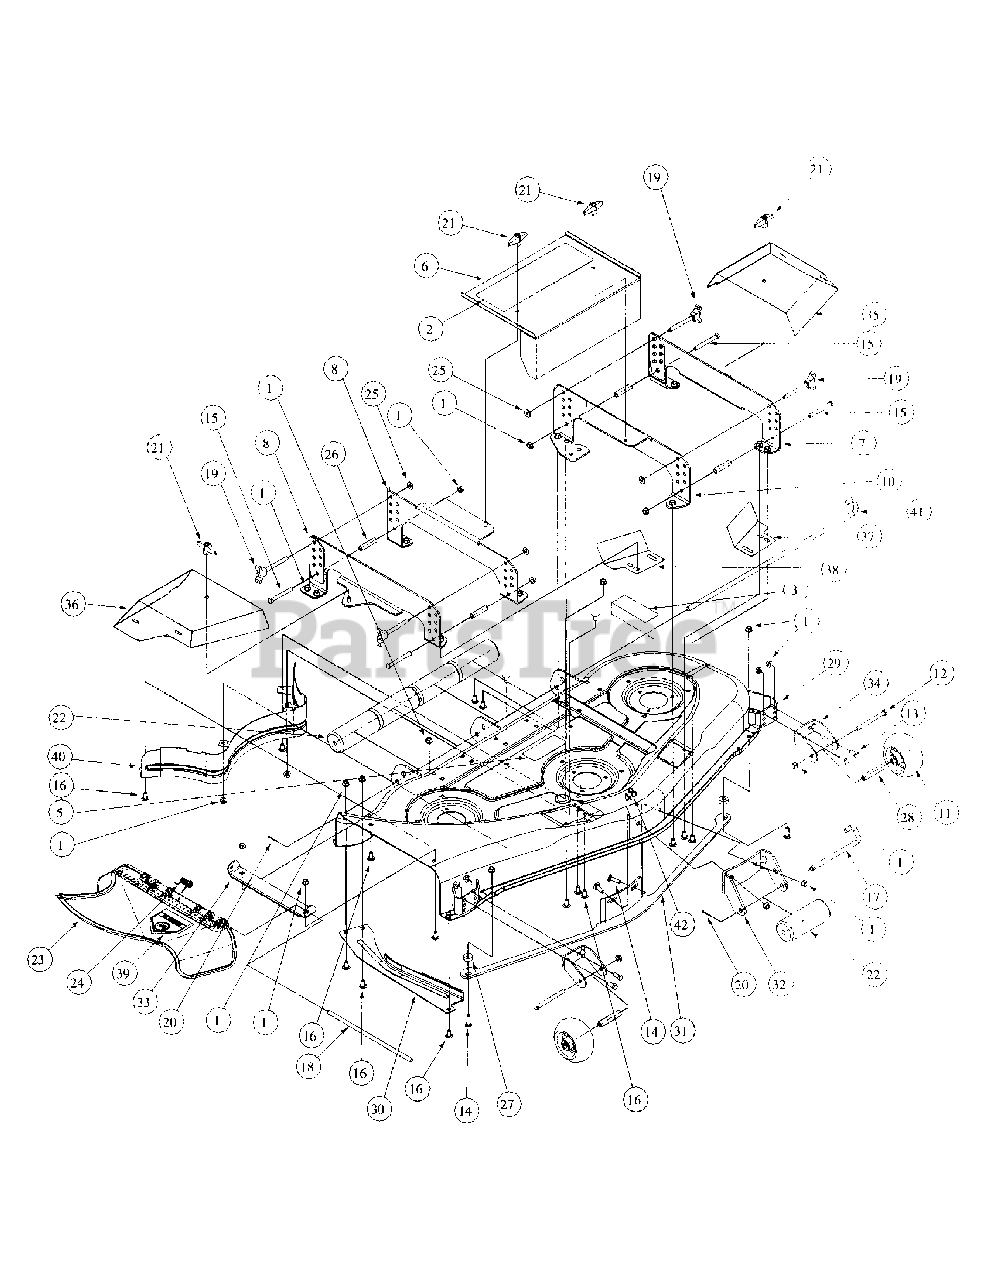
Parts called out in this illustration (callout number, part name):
1	Nut, Hex, 3/8-16 Flange Lock
2	Label MTD Pro
3	Decal, Rotating Blade
4	Decal, Warning Safety
5	Decal, Warning Shield Missing
6	Cover, Belt Center
7	Hanger Assembly, Outer Left Handle
8	Hanger Assembly, Inner Right Handle
10	Hanger Assembly, Inner Left Handle
11	Wheel, Complete, 5.00 Diameter
12	HHCS, 3/8-16, 4.25
13	HHCS, 3/8-16, .88
14	Carrige Screw, 3/8-16x1.25
15	HHCS, 3/8-16, 3.25
16	Carrige Bolt, 3/8-16 x .75 LG
17	Roller Pin, 1/2 Diameter x 7.31 LG
18	Pin Hinge, .375 x 12.93
19	Pin, Quick Release, 3/8 Dia. x 3.1
20	Cotter Pin, 1/8 x 1.0
21	Knob Assembly, Wingnut 5/16-18
22	Front Roller
23	Deflector Chute
24	Torsion Spring
25	Flat Washer, .385 IDx.870 ODx.092
26	Spacer, Stop Deck
27	Spacer, .406 ID x 1.00 OD x .38
28	Spacer Wheel
29	Mower Deck Assembly
30	Weldment, Guard Assembly
31	Weldment Front Bar 48"
32	Front Roller Bracket
33	Mounting Bracket, Chute
34	Castor Bracket
35	Belt Cover, Left Handle, 48"
36	Belt Cover, 48" Deck R.H.
37	Filler Plate, Left Hand
38	Filler Plate, Right Hand
39	Decal, Danger, Hands and Feet
40	Baffle, Right Rear, Inner 48" Deck
41	Roller Pin
42	Label, MTD Pro 48
